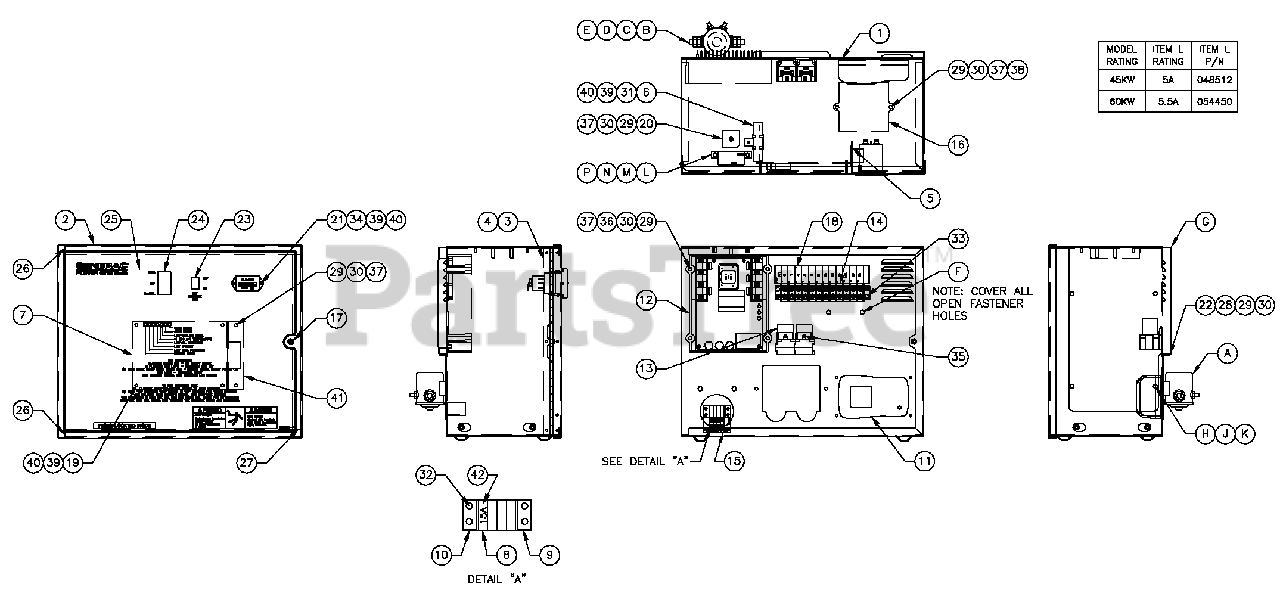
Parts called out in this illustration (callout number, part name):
1	ENCL HSB CONTROL PANEL
2	COVER CONTROL PANEL R-200B
3	HINGE CONTINUOUS H-PANEL
4	RIVET POP .125 X .275 SS
5	SCREW PPPH HI-LO #4-24 X 3/8
6	WASHER FLAT M3
7	ASSY PCB R-200B CNTRL 3600 RPM
8	HOLDER FUSE WICKMANN 178.6150
9	ADPTR RH SIDE WICKMANN 178.6191
10	ADPTR LH SIDE WICKMANN 178.6192
11	BATC 13.4VDC 2.5A W/4POS PLUG
12	ASSY PCB HI-PWR VOLTAGE RGLTR
13	RELAY 12VDC C FORM W/DIODE
14	BLOCK TERM 2 0 A 12 X 6 X1100V
15	DECAL CPL CNT PNL FUSES
16	ASSY PCB BOSCH GOV DRIVER
17	M5X0.8 CAPTIVE PANEL KNLD HD
18	DECAL CPL 3.9LTB1
19	SPACER 9.5H 3.2 ID
20	DIO BRIDGE 25A 600V
21	HOUR METER 10-80VDC
22	PLATE HARNESS CLAMP
23	SWITCH RKR DPST125V SPD
24	SWITCH RKR DPDT ON-OFF-ON
25	DECAL CONTROL FLEX R-200B
26	SEAL COVER 3.18X12.7X382
27	SEAL COVER 3.18X12.7X283
28	SCREW HHPM M5-0.8X12
29	WASHER FLAT M5
30	WASHER LOCK M5
31	RES WW15R 5% 25W QK CONN
32	SCREW PHTTM3.5-0.6X 10
33	SCREW PHTTM3.5-0.6X 16
34	SCREW PHM M3-0.5 X 10 BLACK
35	SCREW PHTT M4-0.7 X 10 ZYC
36	SCREW PPHM M5-0.8X 50 ZNC
37	NUT HEX M5-0.8 G8YEL CHR
38	SCREW PPHM M5-0.8 X 30 SS
39	WASHER LOCK M3
40	NUT HEX M3-0.5 G8YEL CHR
41	SUPPORT ANGLE PCB
42	FUSE ATO TYPE 15 AMP (BLUE)
A	RELAY SOLENOID 12VDCPNLMNT
B	SCREW HHC 1/4-20 X 3/4 G5
C	WASHER FLAT 1/4-M6 ZINC
D	WASHER LOCK M6-1/4
E	NUT HEX 1/4-20 STEEL
F	SEAL WEATHER .45"DIA
G	COVER CONTROL PANEL SIDE
H	SCREW PPHM M5-0.8 X 12 ZNC
J	WASHER LOCK M5
K	WASHER FLAT M5
L	DPEBREAKER
M	WASHER FLAT M3
N	WASHER LOCK M3
P	NUT HEX M3-0.5 G8YEL CHR
